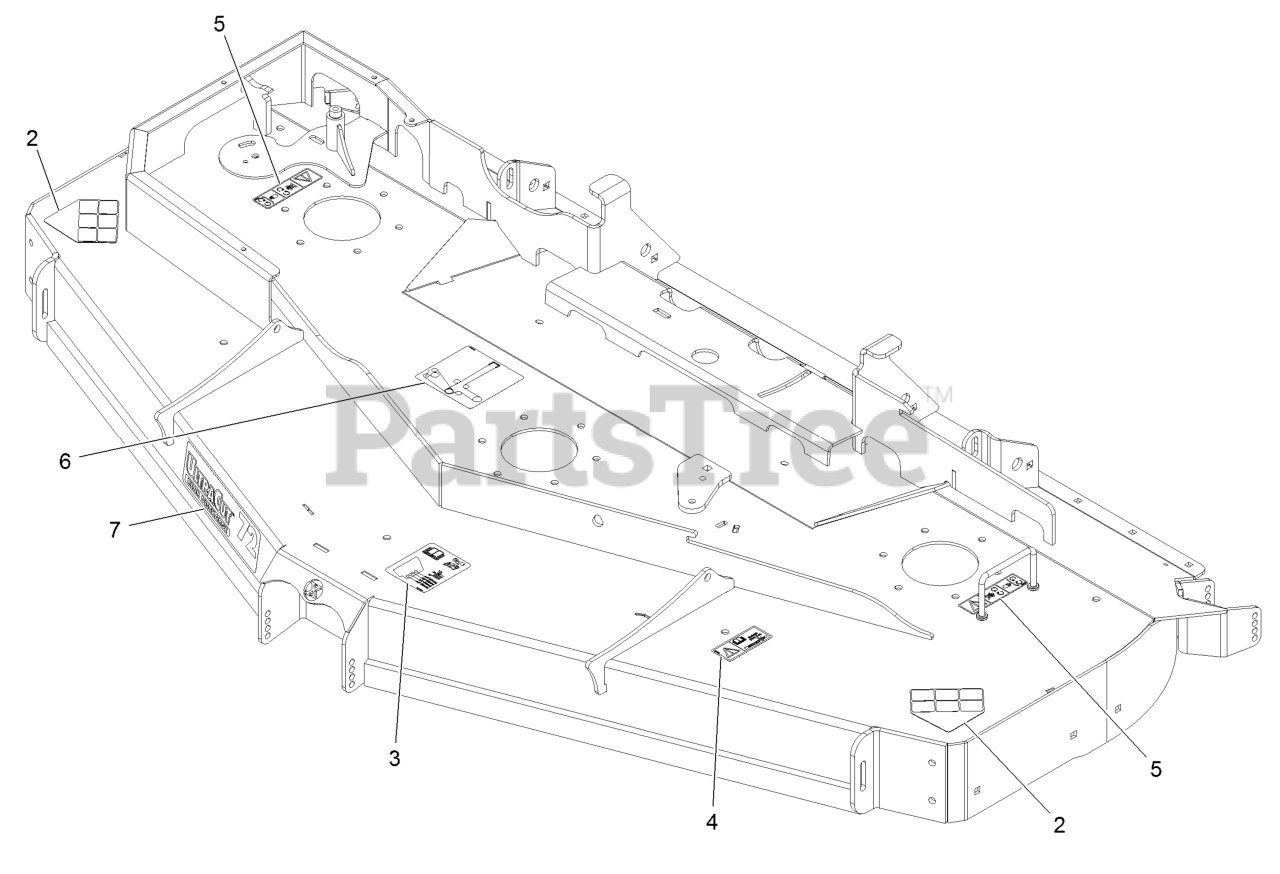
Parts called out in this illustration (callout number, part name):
2	DECAL-DANGER
3	DECAL-ROLLER, ANTI-SCALP
4	DECAL-BOLT TORQUE
5	DECAL-COVER, MISSING
6	DECAL,BELT ROUTING RD DEC
7	DECAL,REAR DISCHARGE 72
